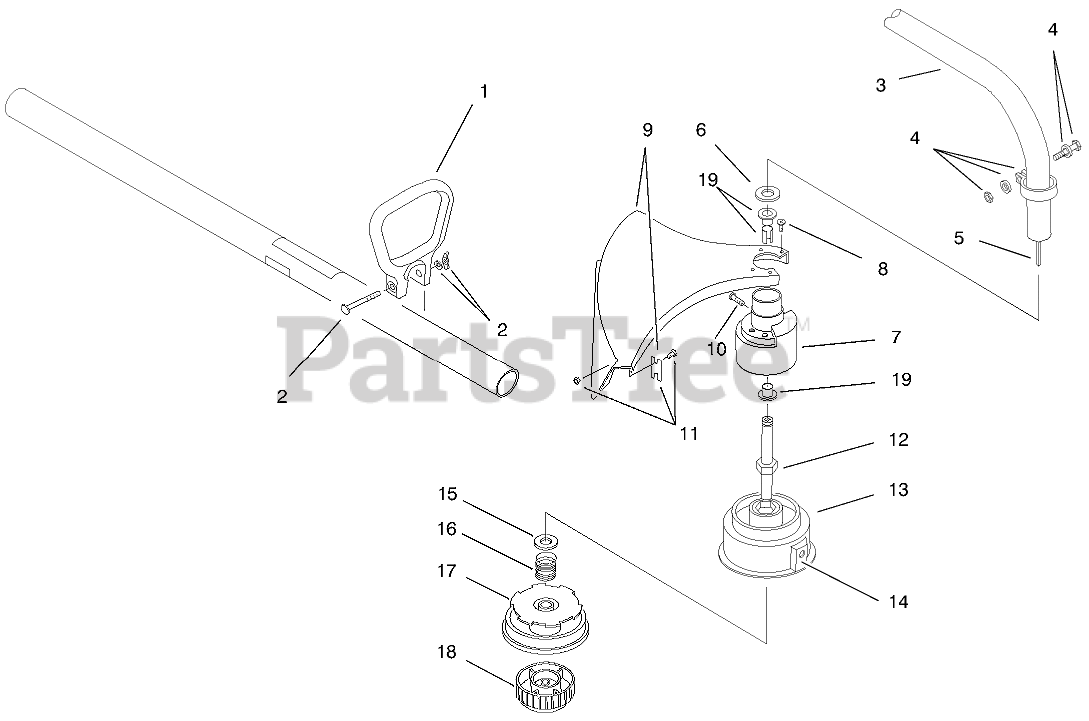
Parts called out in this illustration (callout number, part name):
1	D-HANDLE
2	HARDWARE - D-HANDLE
3	ASM - DRIVE SHAFT HSG
4	Lower Clamp Asm. (Incl. Ref.#10)
5	SHAFT - FLEXIBLE DRIVE
7	Bushing Housing Asm. (Incl. Ref.# 19)
8	GUARD MTG SCREW ASM
9	GUARD/BLADE ASM
10	ANTI-ROTATION SCREW
11	BLADE ASM
12	Shaft-Spool
13	OUTER SPOOL EYELET ASM
14	EYELET
15	RETAINER WASHER(SET OF 10)
17	REEL - INNER
18	SMALL BUMP KNOB ASM
19	Bushing Housing Asm. (Not Serviced Separately)
